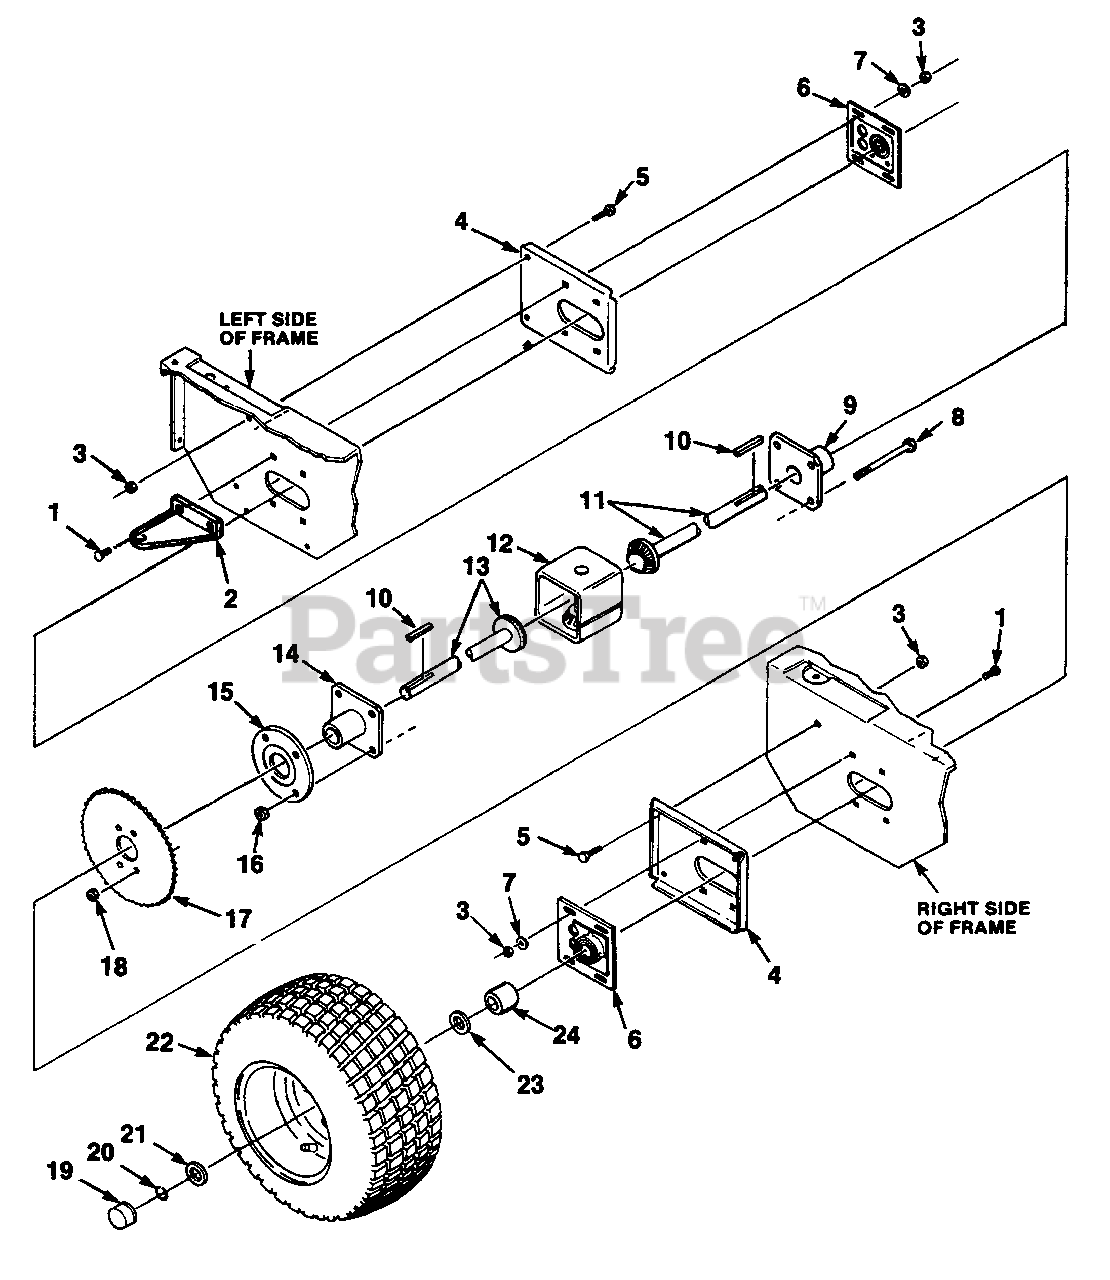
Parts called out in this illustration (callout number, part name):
1	BOLT- 1/4-20 x 3/4
3	NUT- 1/4-20 lock
4	SUPPORT- Frame
5	SCREW 1/4-20 x 5/8
6	RETAINER & BEARING
7	WASHER 1/4
8	BOLT- Hex 5/16-18 x 4
9	CAP & BEARING (L.H.)
10	KEY 3/16 x 3/16 x 2 1/2
11	AXLE- L.H. w/Gear
12	HOUSING & GEARS
13	AXLE- R.H. w/Gear
14	CAP & BEARING (R.H.)
15	SPACER- Differential
17	SPROCKET- 48 tooth
18	NUT- Centerlock 3/8-16
20	RING- Retaining
21	SPACER- Axle
22	TIRE & HUB (rear)
23	WASHER- Flat
